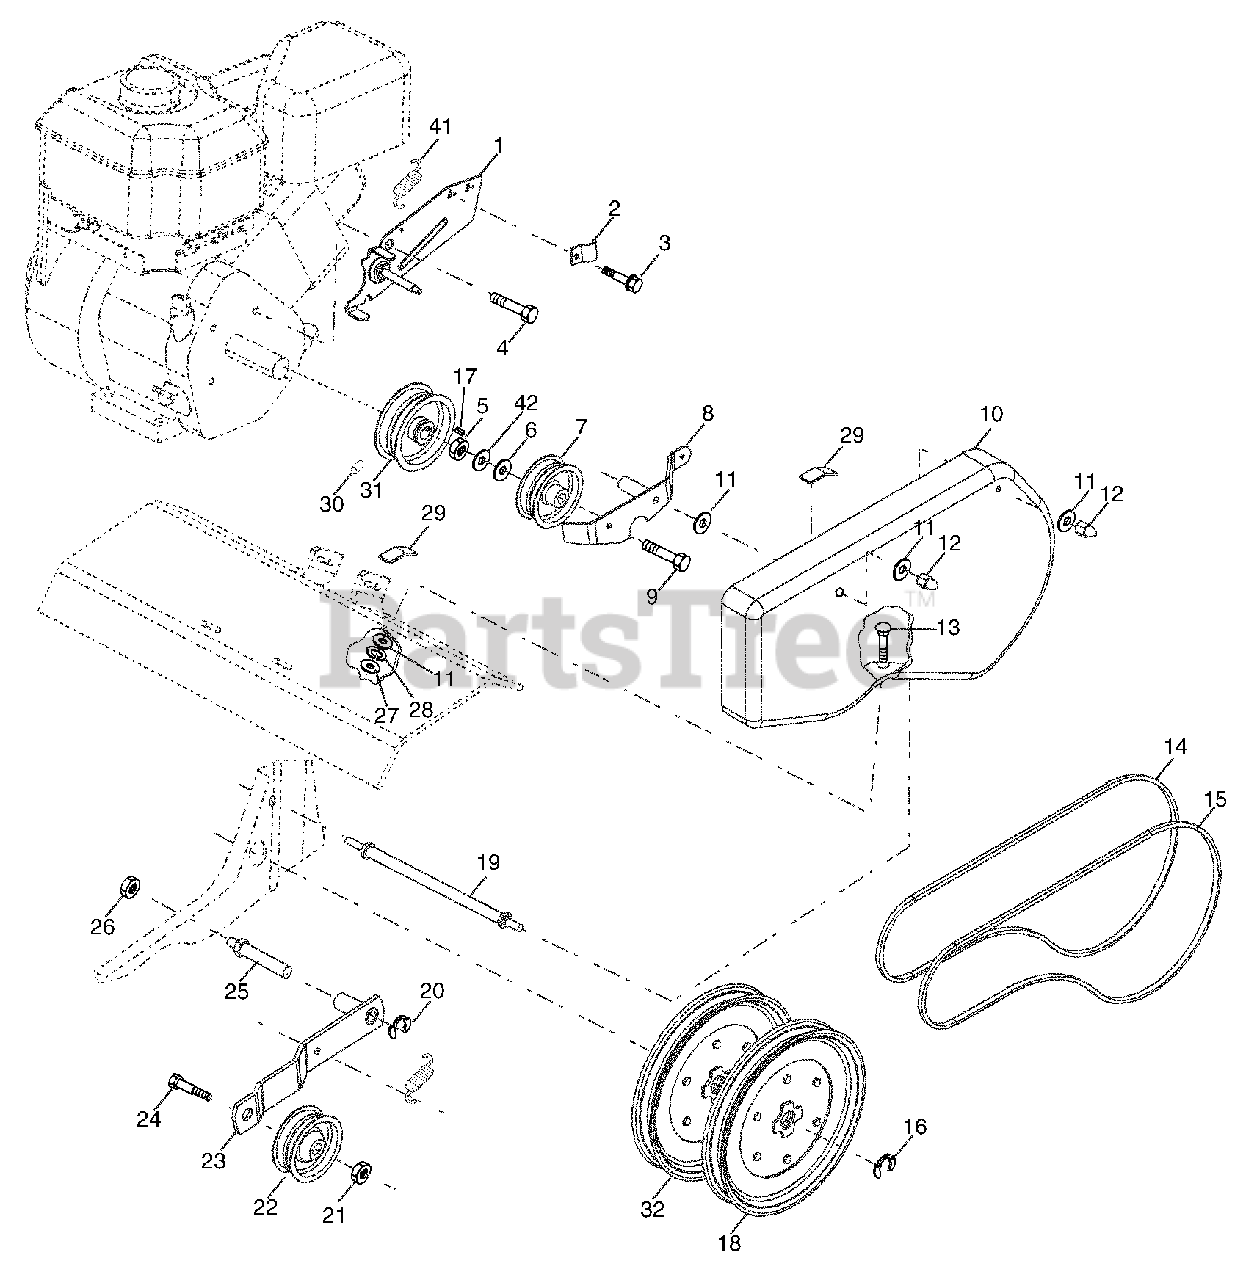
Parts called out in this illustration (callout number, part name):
1	Assembly, Bracket, Belt Guard
2	Clip, Cable
3	Screw, Hex, Washer Hd., Slotted, Thd. Cutting #10-24 x 1/2 Type D
4	Bolt, Hex 1/2-20 x 3/4
5	Nut, Hex Lock 3/8-16
6	Washer 13/32 x 13/16 x 16 Ga.
7	Pulley, Idler, Reverse
8	Assembly, Arm, Reverse Idler
9	Bolt, Hex 3/8-16 x 1-3/4
11	Washer 9/32 x 5/8 x 16 Ga.
12	Nut, Cap 1/4- 20
13	Bolt, Carriage 1/4-20 x 3/4
14	V-Belt (Forward Motion)
15	V-Belt (Reverse)
16	Ring, Retainer
17	Key, Square
18	Pulley, Flat, Trans.
19	Bolt, Belt Guard
20	Ring, Klip
21	Nut, Hex, Jam 3/8-16
22	Pulley, Idler
24	Bolt, Hex 3/8-16 x 1-1/4
25	Shaft, Idler Arm
26	Nut, Hex, Jam 5/16-18
27	Nut, Fin Hex 1/4-20
28	Washer LK Hvy Helical 1/4
29	Pad, Idler
30	Screw, Set, Socket, Headless C.P. 1/4-20 x 1 /4
31	Sheave, Engine
32	Pulley, V-Groove, Trans.
41	Spring
42	Spacer
